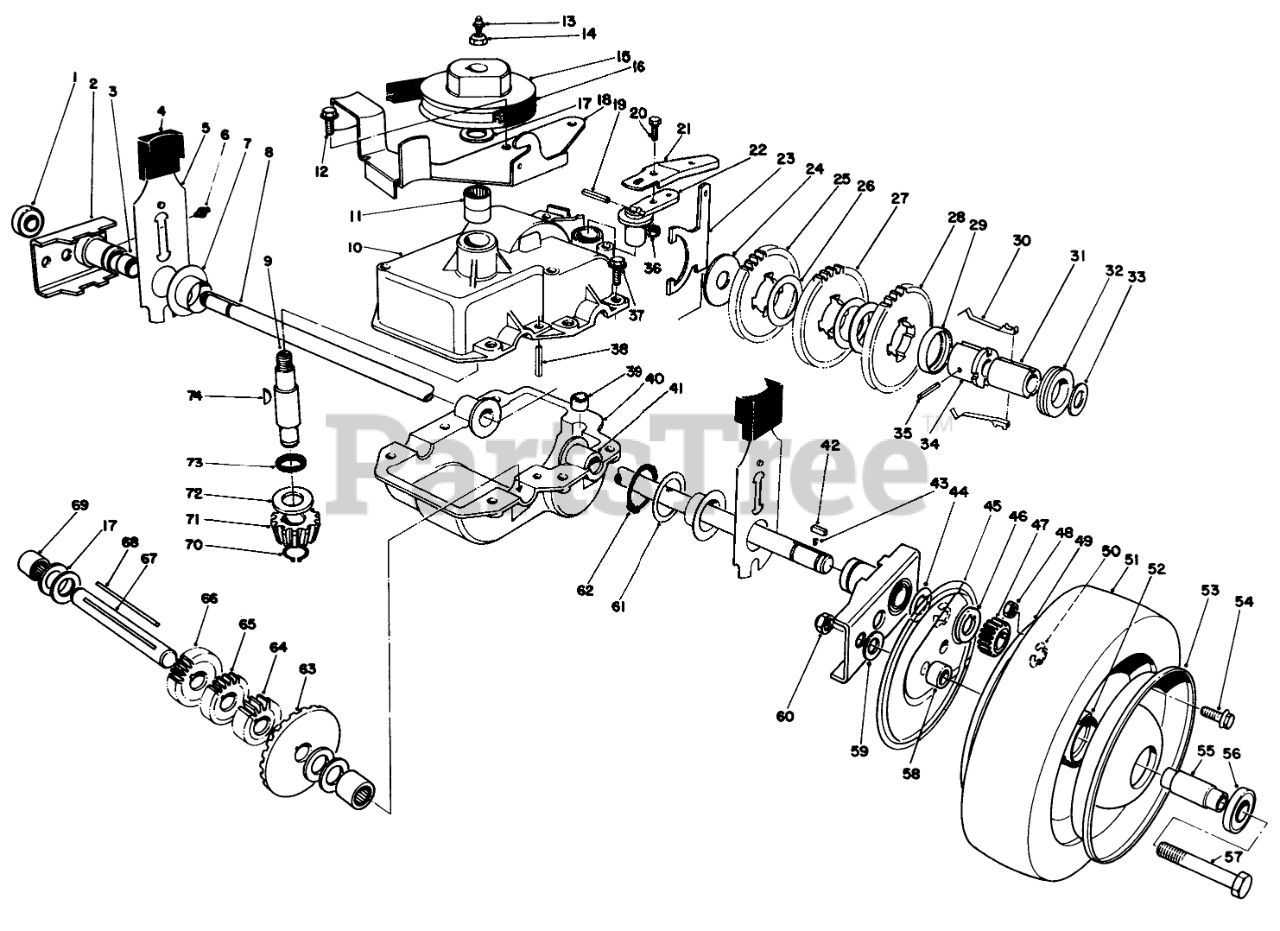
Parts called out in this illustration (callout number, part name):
1	BEARING-WHEEL
2	Pivot Arm Assembly (Incl. Ref. #1,3 & 6)
3	BUSHING
4	KNOB-ARM
5	REAR SPRING ARM ASM
6	FITTING-GREASE
7	CAP-END
8	Shaft-Output
9	Shaft Input
10	Upper Case Assembly (Incl. Ref. #11 & 73)
11	BEARING-NEEDLE
12	SCREW
13	FITTING-GREASE
14	NUT-HEX
15	PULLEY
16	V-BELT
17	WASHER-THRUST
18	Belt Guide Bracket
19	PIN-COIL
21	SHIFT LEVER COVER
22	LEVER-SHIFT
23	Shift Yoke
24	WASHER
25	GEAR-38T
26	WASHER
27	GEAR-42T
29	RETAINER-KEY
30	KEY-SHIFT
31	SLEEVE
32	COLLAR-SHIFT
33	WASHER-PLAIN
34	SLEEVE-GEAR
35	PIN-GROOVE
36	NUT-LOCK, NI
37	SCREW-HWHTF
38	ROLL PIN 3/16 X 1 IN
39	BUSHING-YOKE
40	Case-Lower
41	BUSHING
42	KEY RECTANGULAR
43	SPRING-COMPRESSION
44	WASHER-THRUST, OUTER
45	WHEEL COVER
46	WASHER-THRUST, OUTER
47	GEAR-PINION
48	NUT-LOCK, NI
49	Wheel-Half
50	RING-RETAINING
52	HUB-BEARING
53	Wheel-Half
54	SCREW-HHF
55	SPACER-BEARING
56	BEARING-WHEEL
57	SCREW-HH
58	SPACER-WHEEL
59	WASHER
60	NUT-LOCK, CONE
61	WASHER
62	RING-RETAINING
63	BEVEL GEAR
64	GEAR-12T
65	GEAR-14T
66	GEAR-18T
67	SHAFT-INTERMEDIATE
69	BEARING-NEEDLE, CLOSED
70	RING-RETAINING
71	PINION-BEVEL
72	WASHER-THRUST
74	KEY-WOODRUFF
